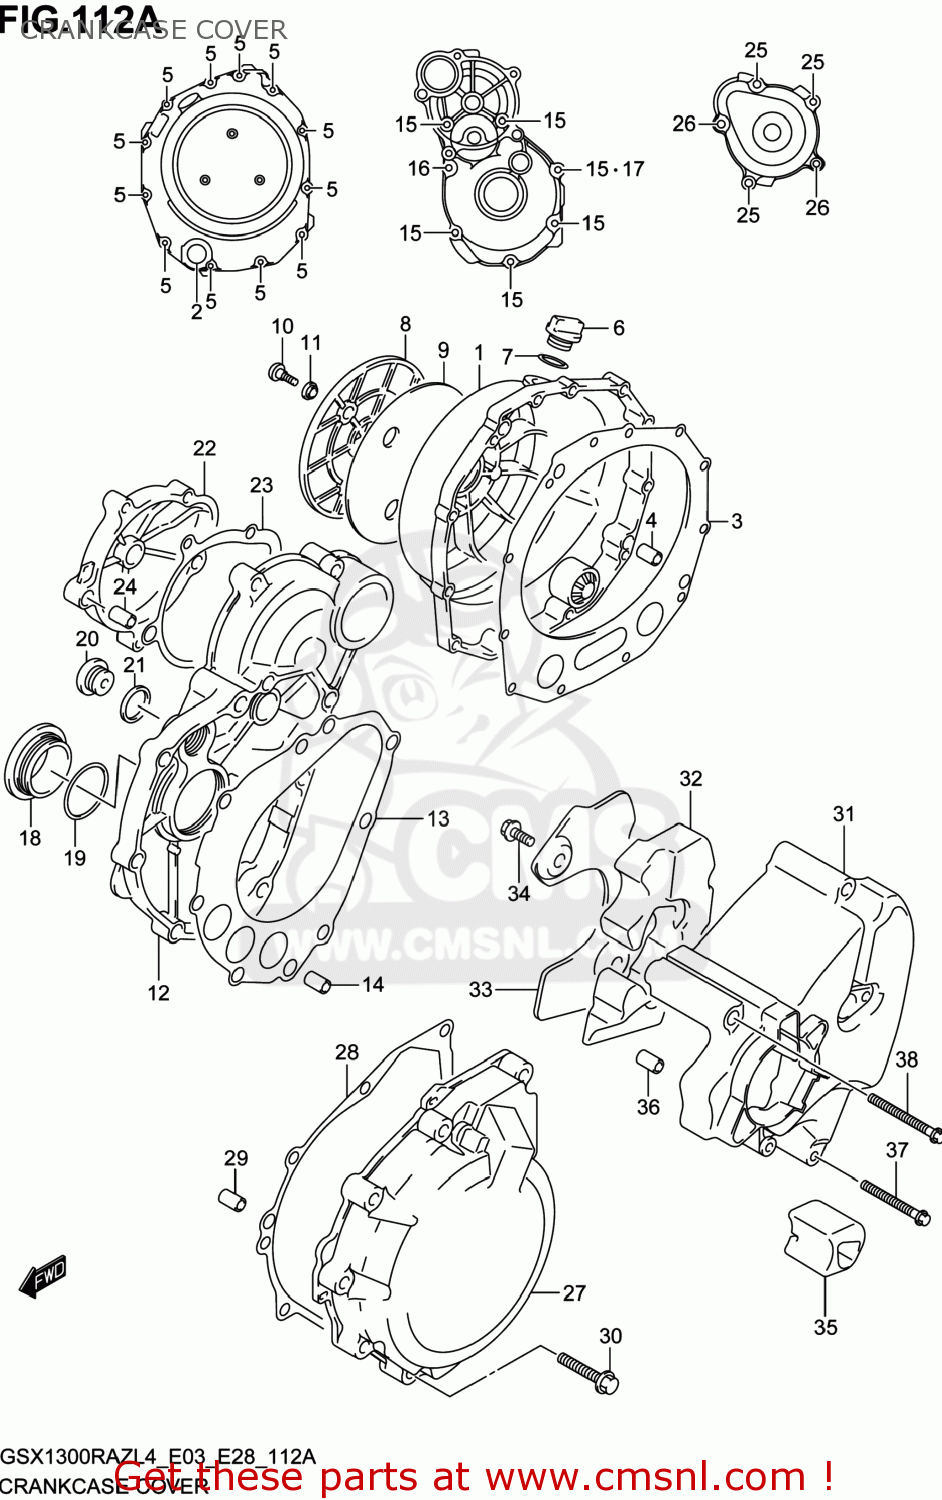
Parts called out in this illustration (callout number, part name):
1	COVER,CLUTCH
2	LENS,OIL LEVEL CHECK
3	GASKET,CL COVER (NAS)
4	PIN
5	BOLT(6X30)
6	PLUG,ENGINE OIL FILLER
7	O RING(D:3.1,ID:16.8)
8	COVER,CLUTCH OUTER
9	CUSHION,CLUTCH OUTER COVER
10	SCREW(6X16)
11	WASHER,CLUTCH OUTER COV SCREW
12	COVER,STARTER CLUTCH
13	GASKET,STARTER CLUTCH COVER (NAS)
14	PIN
15	BOLT(6X25)
16	BOLT(6X35)
17	GASKET(5.8X13X1.2) (NAS)
18	PLUG
19	O RING(D:3.1,ID:32.7)
20	PLUG,16X8
21	GASKET(16X22X2) (NAS)
22	CAP,STARTER IDLE GEAR
23	GASKET,START IDLE GEAR CAP (NAS)
24	PIN
25	BOLT(6X25)
26	BOLT(6X35)
27	COVER,MAGNETO
28	GASKET,MAGNETO COVER (NAS)
29	PIN
30	BOLT(6X30)
31	COVER,ENGINE SPROCKET
32	DAMPER,ENG SPROCKET COVER
33	PLATE,ENGINE SPROCKET COVER
34	BOLT(6X12)
35	PROTECTOR,ENGINE SPRKT COVER
36	PIN
37	BOLT(6X55)
38	BOLT(6X65)
